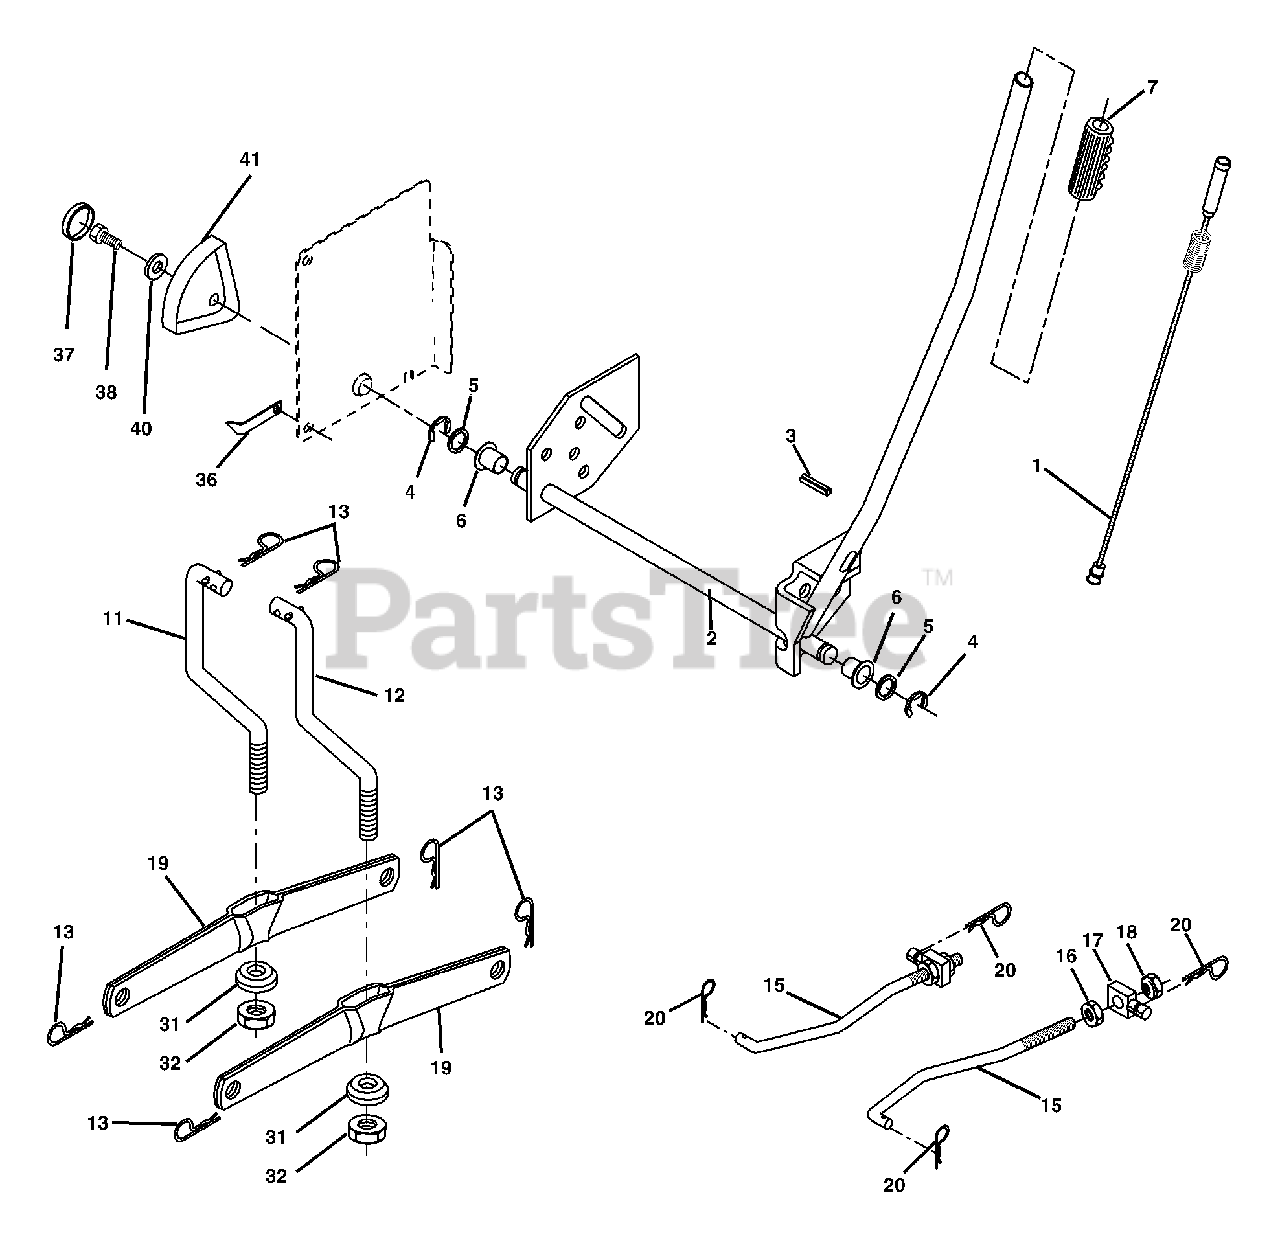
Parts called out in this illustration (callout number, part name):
1	Plunger Assembly
2	Shaft Assembly, Lift
3	Pin, Groove
5	Washer 21/32 x 1 x 21 Ga.
6	Bearing, Nylon
7	Grip, Handle, Fluted
11	Link, Lift, L.H.
12	Link, Lift, R.H.
13	Retainer Spring
15	Link Front Sus.
16	Nut Hex Jam 1/2-13 unc
17	Trunnion Front Susp.
18	Nut Lock w/Wsh 1/2-13 unc
19	Arm Asm. Suspension Mower
20	Retainer Spring
31	Bearing Pivot Lift
32	Nut Crownlock 3/8-24
36	Pointer Height Indicator
37	Plug Hole
38	Screw 5/16-18 x 1
40	Washer 11/32 x 1-1/2 x 10 Ga.
41	Indicator Height Stlt
